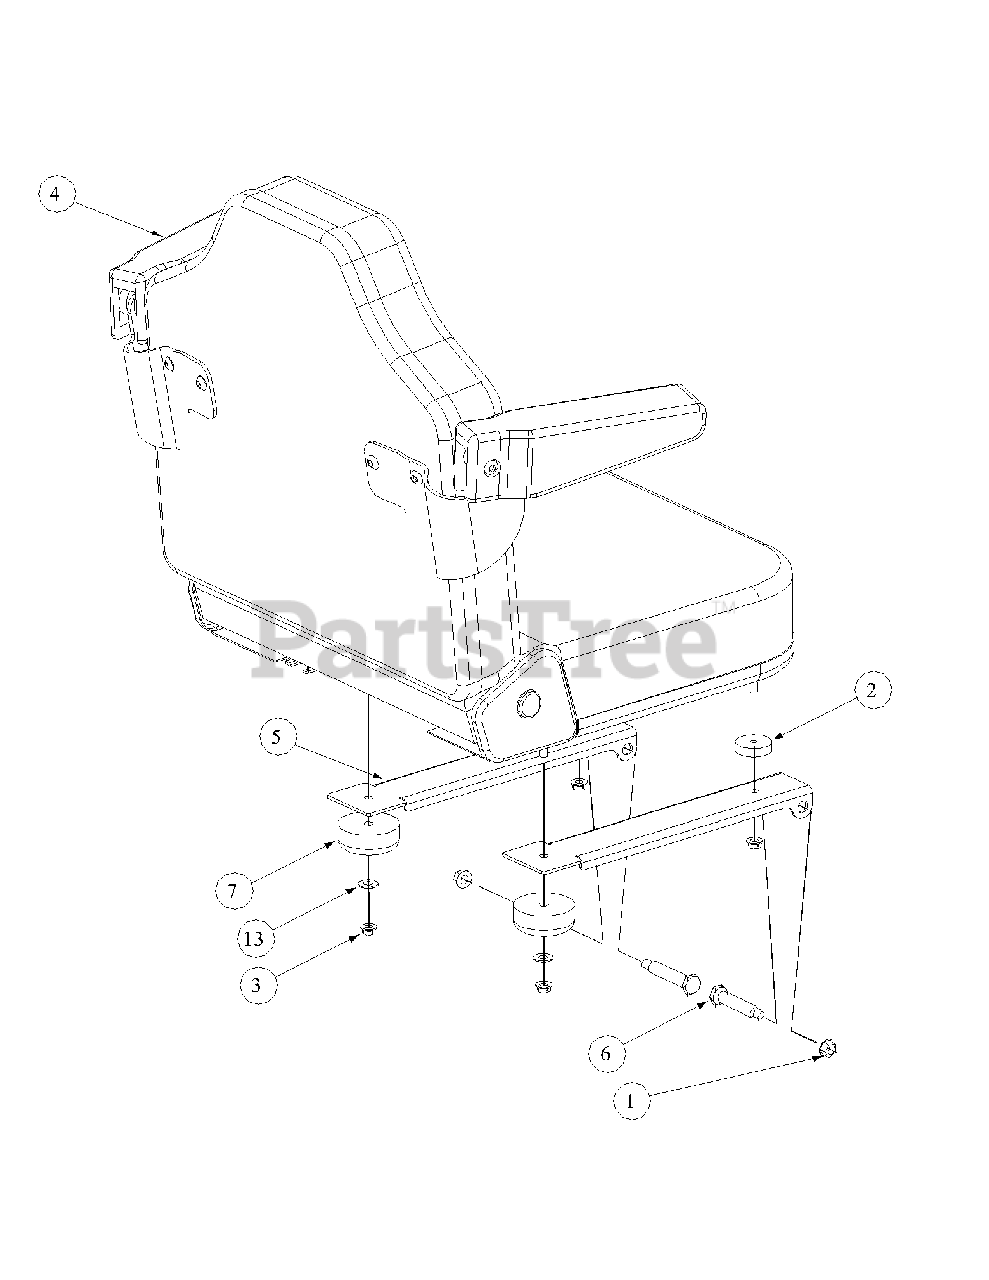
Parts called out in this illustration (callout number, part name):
1	Nut, Hex 3/8-16 Flange Lock
2	Spacer, 0.345 ID x 1.50 OD x .41
3	Lock Nut, Hex Flange, 5/16-18
4	Adjustable Seat, Black embossed,
5	Mounting Bracket, Seat
6	Shoulder Screw, .50x2.345, 3/8-16
7	Grommet, 2.5 OD x 1.0 Long
13	Washer
